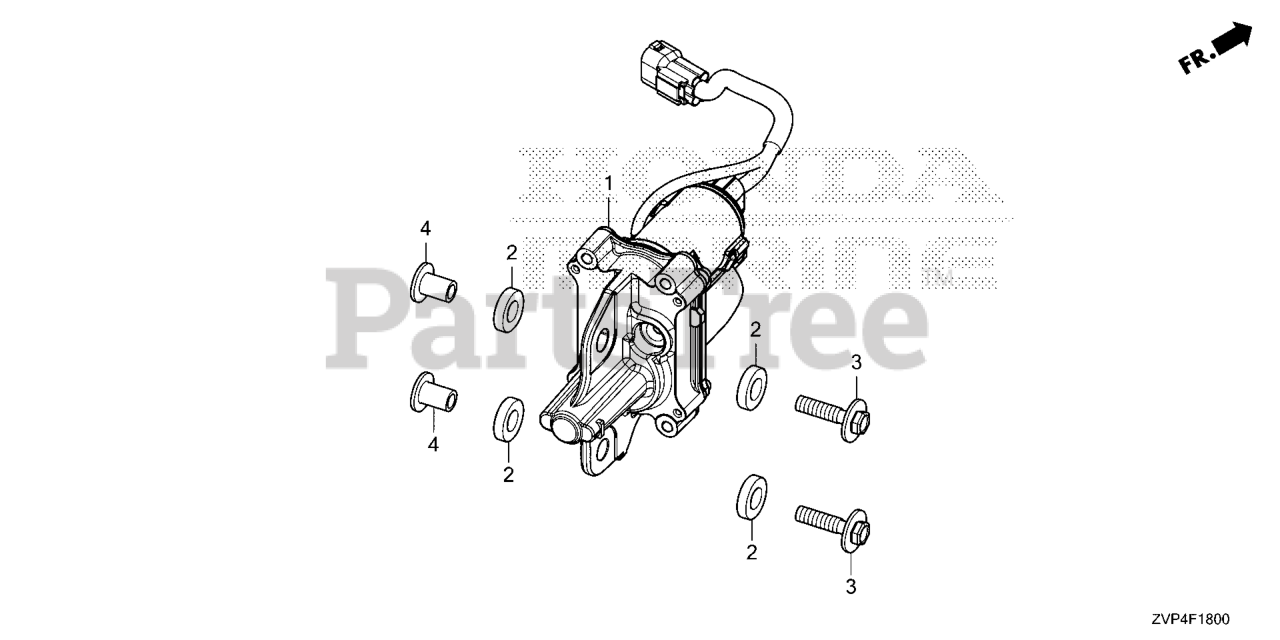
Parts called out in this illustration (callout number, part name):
1	ACTUATOR, SHIFT
2	RUBBER, CUSHION
3	BOLT-WASHER (8X35)
4	COLLAR (8X17)
